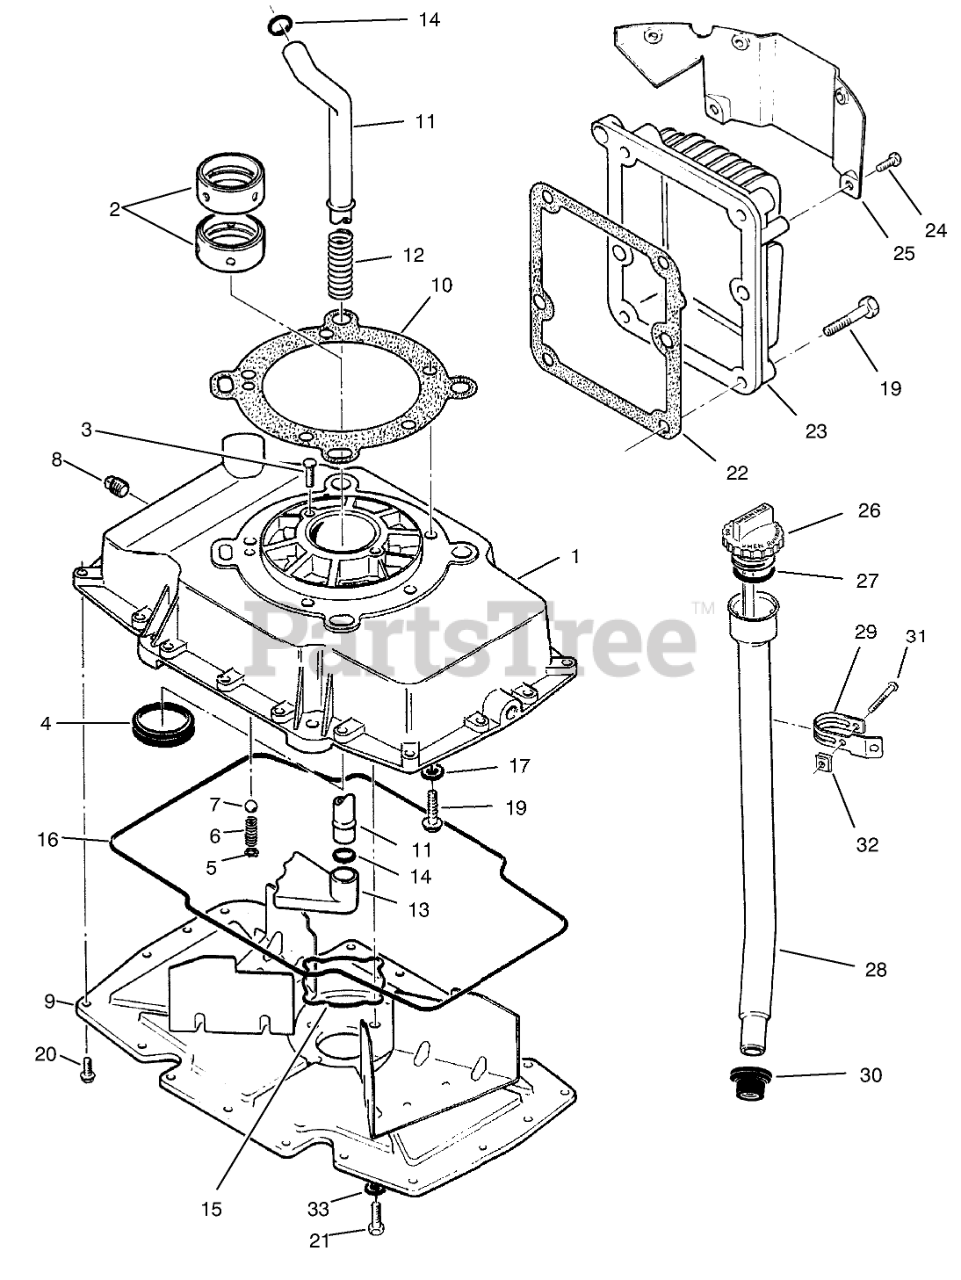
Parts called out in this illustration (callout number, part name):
1	Base-Oil (Incl. Ref. #2-7)
2	BEARING KIT (STANDARD SLEEVE)
3	Screw
4	OIL-SEAL
5	RETAINING-RING
6	SPRING
7	BALL-BEARING
8	Plug
9	OIL-BASE COVER ZINC
10	OIL-BASE GASKET
11	OIL-PICKUP TUBE
12	OIL-PICKUP SPRING
13	OIL-PICKUP CUP
14	O-RING
15	OIL-SEAL
16	OIL-SEAL
17	Washer
19	HEX-HEAD CAP SCREW
20	SCREW-HH
21	SCREW-HWH
22	Gasket
23	OIL-COOLER
24	HEX HD CAPSCREW
25	OIL-COOLER BAFFLE
26	Indicator-Oil Level (Incl. Ref. #27)
27	SEAL 0-RING
28	OIL-FILL TUBE (ZINC)
29	SUPPORT-BRKT (ZINC)
30	Seal
31	Screw
32	Nut
33	WASHER
